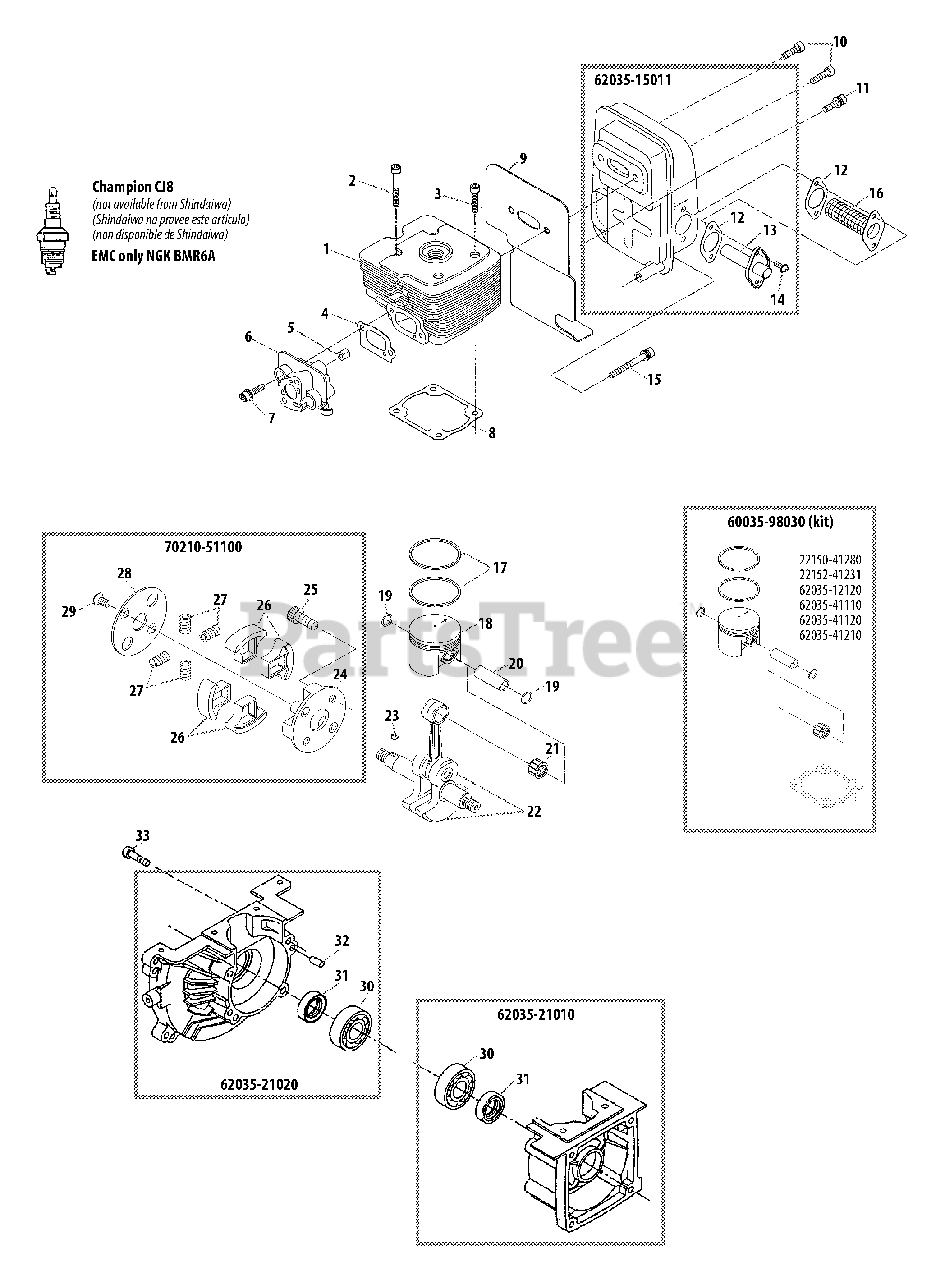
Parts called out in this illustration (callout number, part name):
1	CYLINDER
2	SCREW - 5×35
3	BOLT 5×25
4	GASKET, INTAKE
5	NUT
6	INSULATOR, INTAKE
7	BOLT M5×25
8	GASKET, CYLINDER
9	HEAT SHIELD, EXHAUST
10	BOLT 6×25
11	BOLT M5×16
12	GASKET, EXHAUST
13	PIPE, EXHAUST
14	SCREW
15	BOLT M5×45
16	SCREEN, SPARK ARRESTER
17	RING, PISTON
18	PISTON
19	RING, SNAP
20	PIN, PISTON
21	BEARING, NEEDLE
22	CRANKSHAFT
23	KEY, WOODRUFF 3×10
24	BOSS, CLUTCH
25	BOLT, CLUTCH
26	SHOE, CLUTCH
27	SPRING, CLUTCH
28	PLATE, CLUTCH
30	BEARING, BALL
31	SEAL, OIL 16
32	PIN, LOCATING 5×10
33	BOLT 5×30
60035-98030	PISTON ASSY
62035-15011	MUFFLER ASSY
62035-21010	CRANKCASE ASSY, S
62035-21020	CRANKCASE ASSY, M
70210-51100	CLUTCH ASSY
